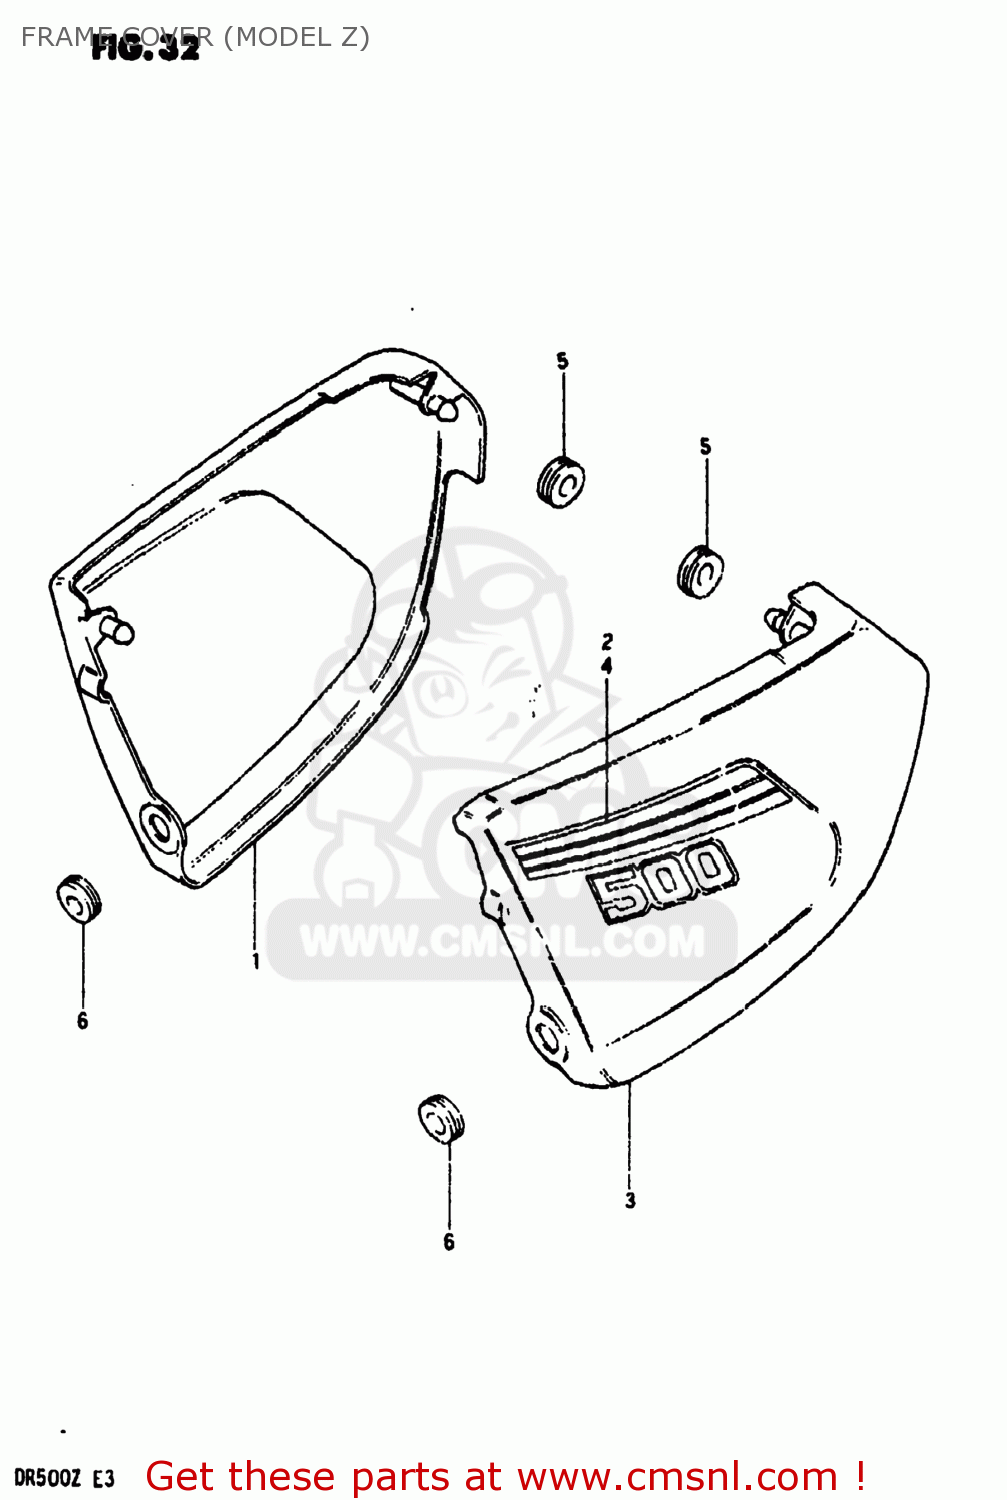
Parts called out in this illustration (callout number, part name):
1	COVER,FRAME,RIGHT
2	TAPE,FRAME COVER
3	COVER,FRAME,LEFT
4	TAPE,FRAME COVER
5	CUSHION
6	CUSHION
